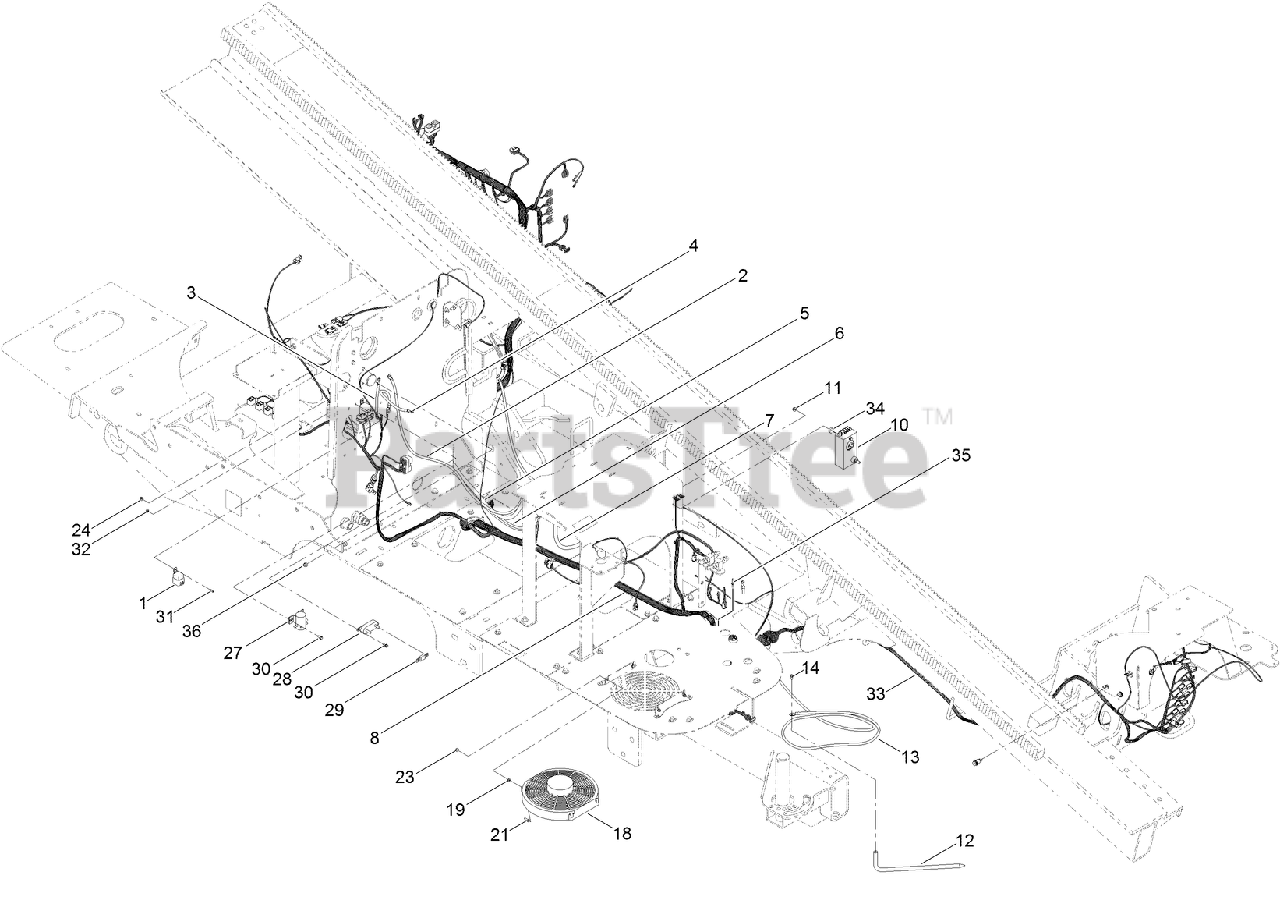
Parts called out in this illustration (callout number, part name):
1	RELAY
2	CABLE-BATTERY, POSITIVE
3	CABLE-BATTERY, POSITIVE
4	CABLE-BATTERY, POSITIVE
5	CABLE-BATTERY, POSITIVE
6	CABLE-BATTERY, NEGATIVE
7	CABLE-BATTERY, NEGATIVE
8	HARNESS-WIRE, MAIN
11	NUT-HF, NI
12	BAR-STAKE, GROUND
13	CABLE-ALERT, STRIKE
14	SCREW-HHF
18	FAN-ELECTRIC
19	WASHER-FLAT
21	SCREW-HH
23	NUT-HF
24	NUT-FLANGE, NI
27	SOLENOID-RELAY 12V, 300A
28	HOLDER-FUSE
29	FUSE-100A
30	SCREW-HHF
31	SCREW-HSBH
32	NUT-HF
33	HARNESS-WIRE, THRUST FRAME
34	SPACER-PIN, MOUNTING
35	RIVET-POP
36	NUT-LOCK, HHF
